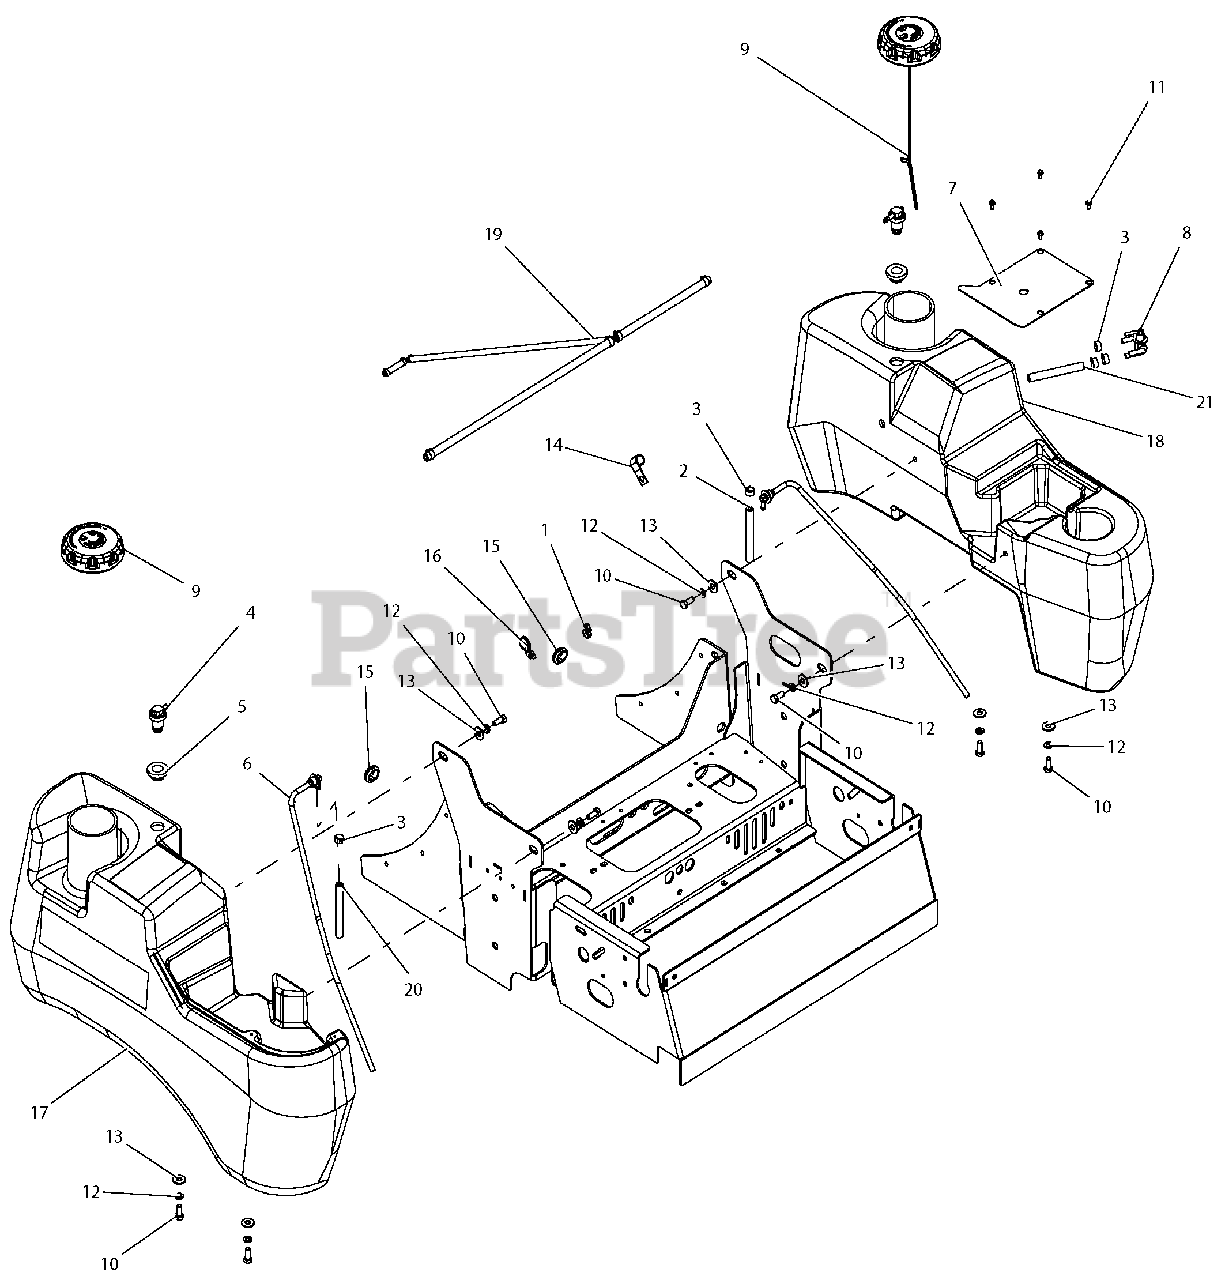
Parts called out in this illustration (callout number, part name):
1	CLIP, ROUTING (.50 ID)
2	.25 LOW-PERM GAS HOSE 19.00" LG - LH TANK TO VALVE
3	CLAMP, FUEL LINE
4	VALVE, COMBINATION
5	GROMMET, REMOTE VENT NITRILE
6	ASM, LARGE TANK FUEL PICKUP
7	PLATE, FUEL VALVE MOUNTING-RED
8	VALVE, FUEL
9	CAP, FUEL VENT-IN AUTOLOCK
10	BLT-HEX .31-18X.75 GR5 YWZC
11	SCR-MCH 10-24X.38 HWHSTAINLESS
12	WSHR-LK .31X.078 REG YWZC
13	WSHR-FL-STL.38X.875X.083 YWZC
15	GROMMET, RUBBER
16	CABLE TIE W/ TREE (.25 HOLE)
17	TANK, RH LARGE GRAVELY FUEL
18	TANK, LH LARGE GRAVELY FUEL
19	PT400, FUEL LINE ASSEMBLY
20	.25 LOW-PERM GAS HOSE 54.00" LG - RH TANK TO VALVE
21	.25 LOW-PERM GAS HOSE 28.00" LG - Valve to engine
